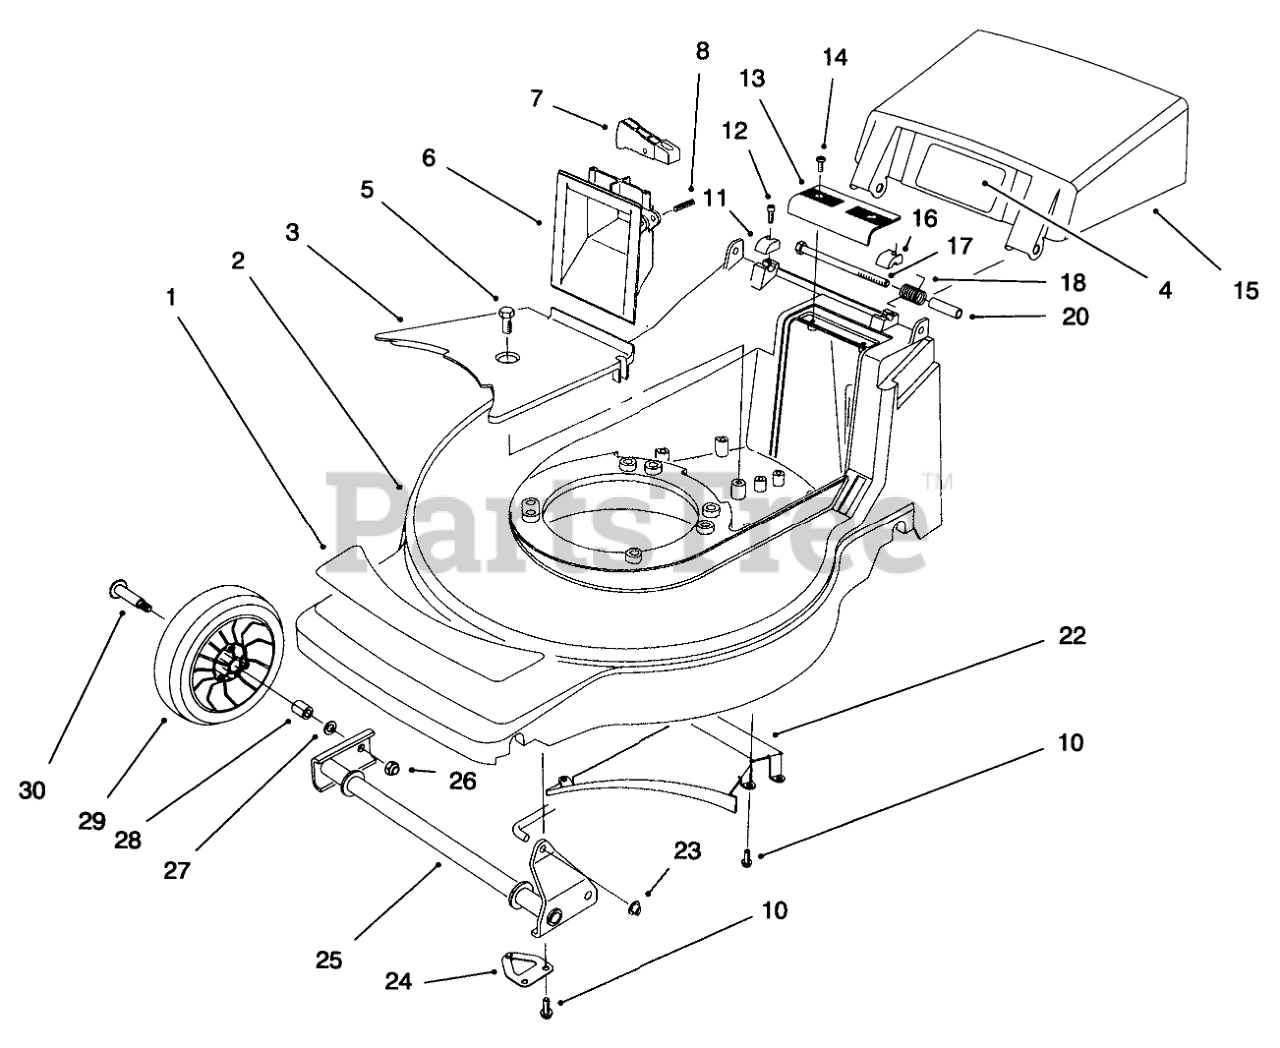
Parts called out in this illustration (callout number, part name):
1	DECAL - DECK 48 CM
2	HOUSING W/DECAL RED
3	BELT COVER
4	DECAL-DANGER
5	SCREW-HWHTF
6	GRIP - LOWER
7	TRIGGER - HOC
8	PIN-SPIRAL
10	SCREW-HWH
11	CAP-HINGE BOLT, RH
12	SCREW-HSH
13	GRIP-UPPER
14	SCREW-PPH, PLASTITE
15	Door Discharge
16	CAP-HINGE BOLT, LH
17	SCREW-HH
18	SPRING-DOOR
20	SPACER-DOOR
22	Ramp-Discharge
23	NUT-PUSH
24	SHAFT RETAINER ASM
25	FRONT PIVOT WA
26	NUT-HEX
27	WASHER
28	BUSHING
29	Wheel & Tire Assembly (Incl. Ref. #28)
30	BOLT-WHEEL
